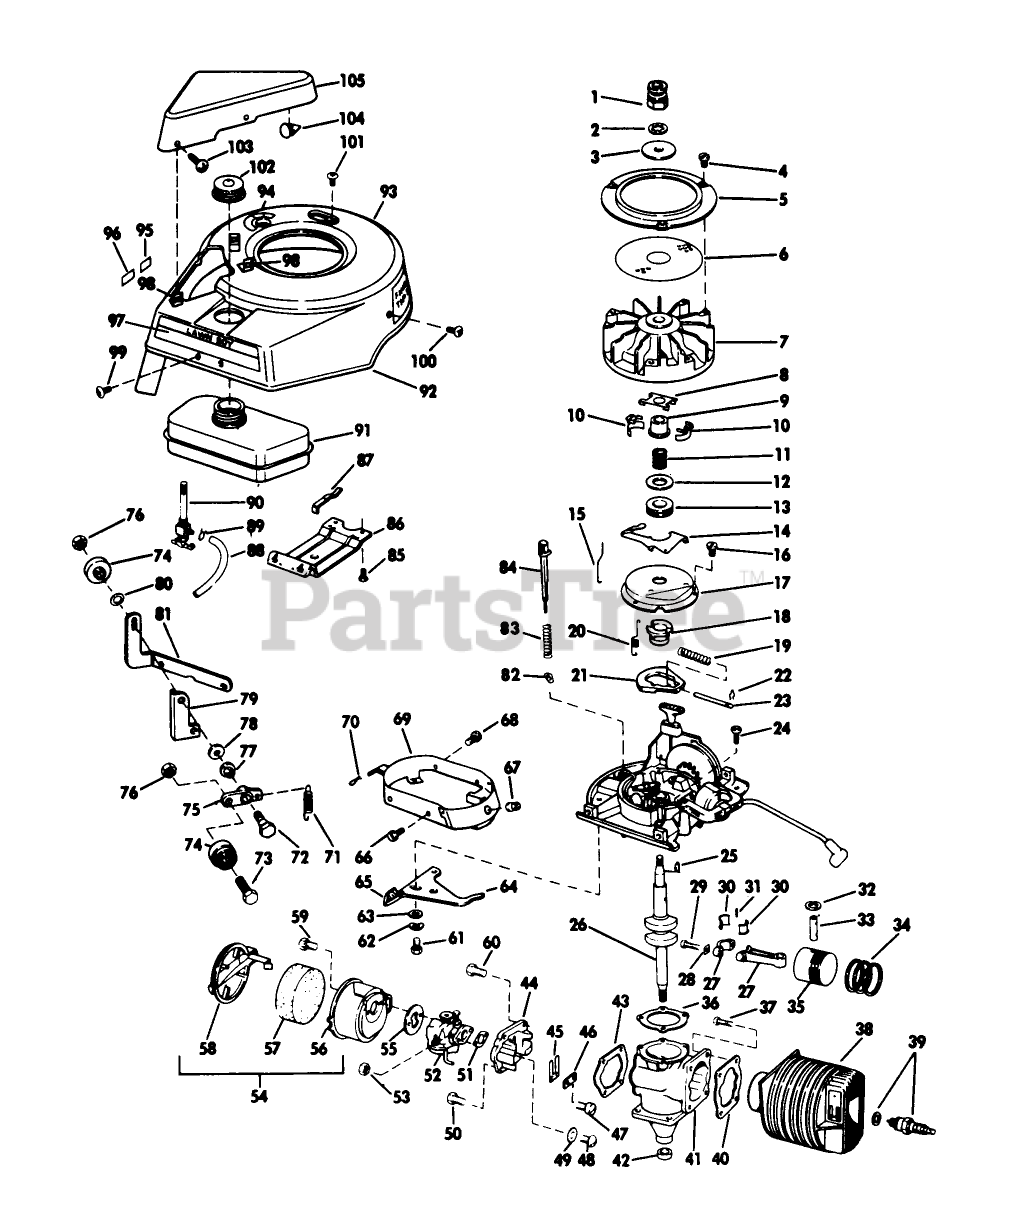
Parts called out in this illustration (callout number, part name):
5	Ring-Flywhl. Scrn.
9	COLLAR S
11	SPRING S
13	THRUST COLLAR S
14	LEVER-GOVERNOR S
16	SCREW S
17	DUST COVER S
18	SPARK ADV. S
19	SPARK ADV. SPRING S
21	FLYWEIGHT S
22	SPARK ADJ. SPRING
23	PIN,SPARK ADV. S
30	LINER ASM
32	RING-RETAINING
36	GASKET S
40	GASKET S
46	PLATE-BACKUP, REED
50	SCREW S
51	GASKET S
53	STOP NUT
57	AIR FIL.ELEM S
59	SCREW S
60	SCREW S
66	SCREW S
67	NUT-CLIP
83	SPRING S
85	SCREW S
88	GAS LINE
89	CLAMP - HOSE S
90	VALVE&SCREEN SM
100	SCREW S
